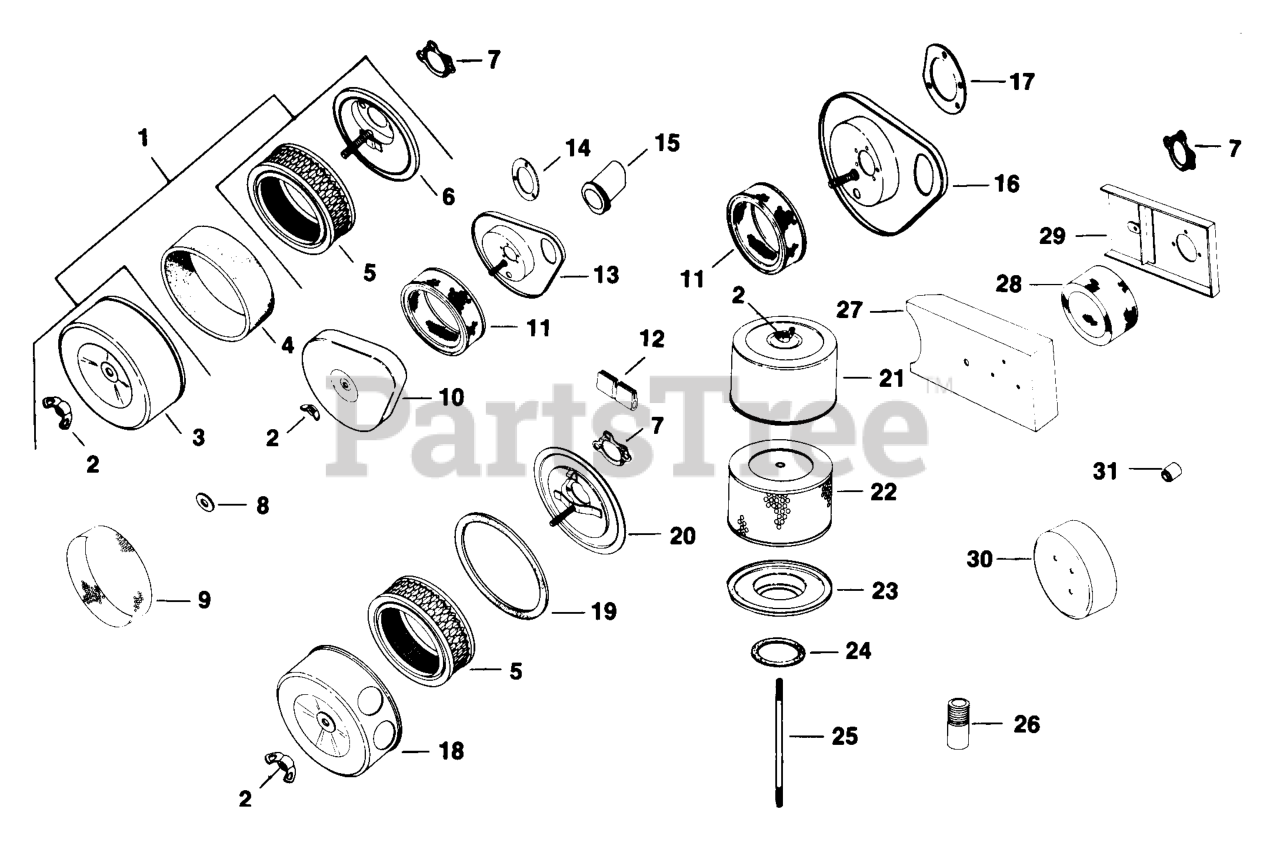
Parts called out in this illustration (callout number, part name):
1	CLEANER - DISCONTINUED
2	NUT, WING 1/4-20 USE 25 100 15-S
3	COVER, AIR CLEANER - DISCONTINUED
5	AIR FILTER/PRE-CLEANER KIT USE 25 883 03-S1
6	BASE, AIR CLEANER - DISCONTINUED
